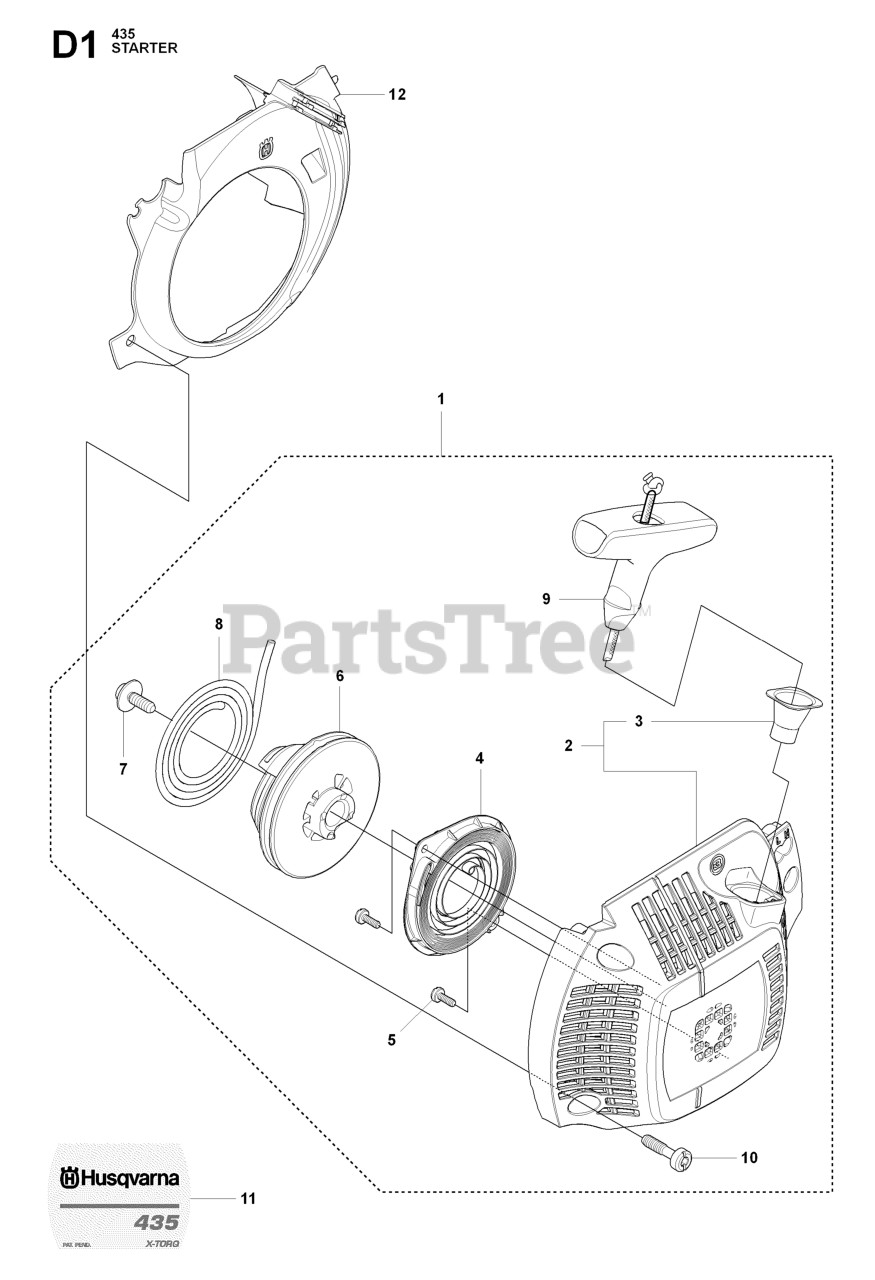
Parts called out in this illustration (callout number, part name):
1	STARTER ASSY
2	HOUSING STARTER
3	SLEEVE
4	SPRING CASSETTE ASSY
5	SCREW
6	STARTER PULLEY
7	SCREW
8	STARTER ROPE
9	HANDLE
10	SCREW
11	LABEL 435
12	%COOLING AIR CONDUCTOR
